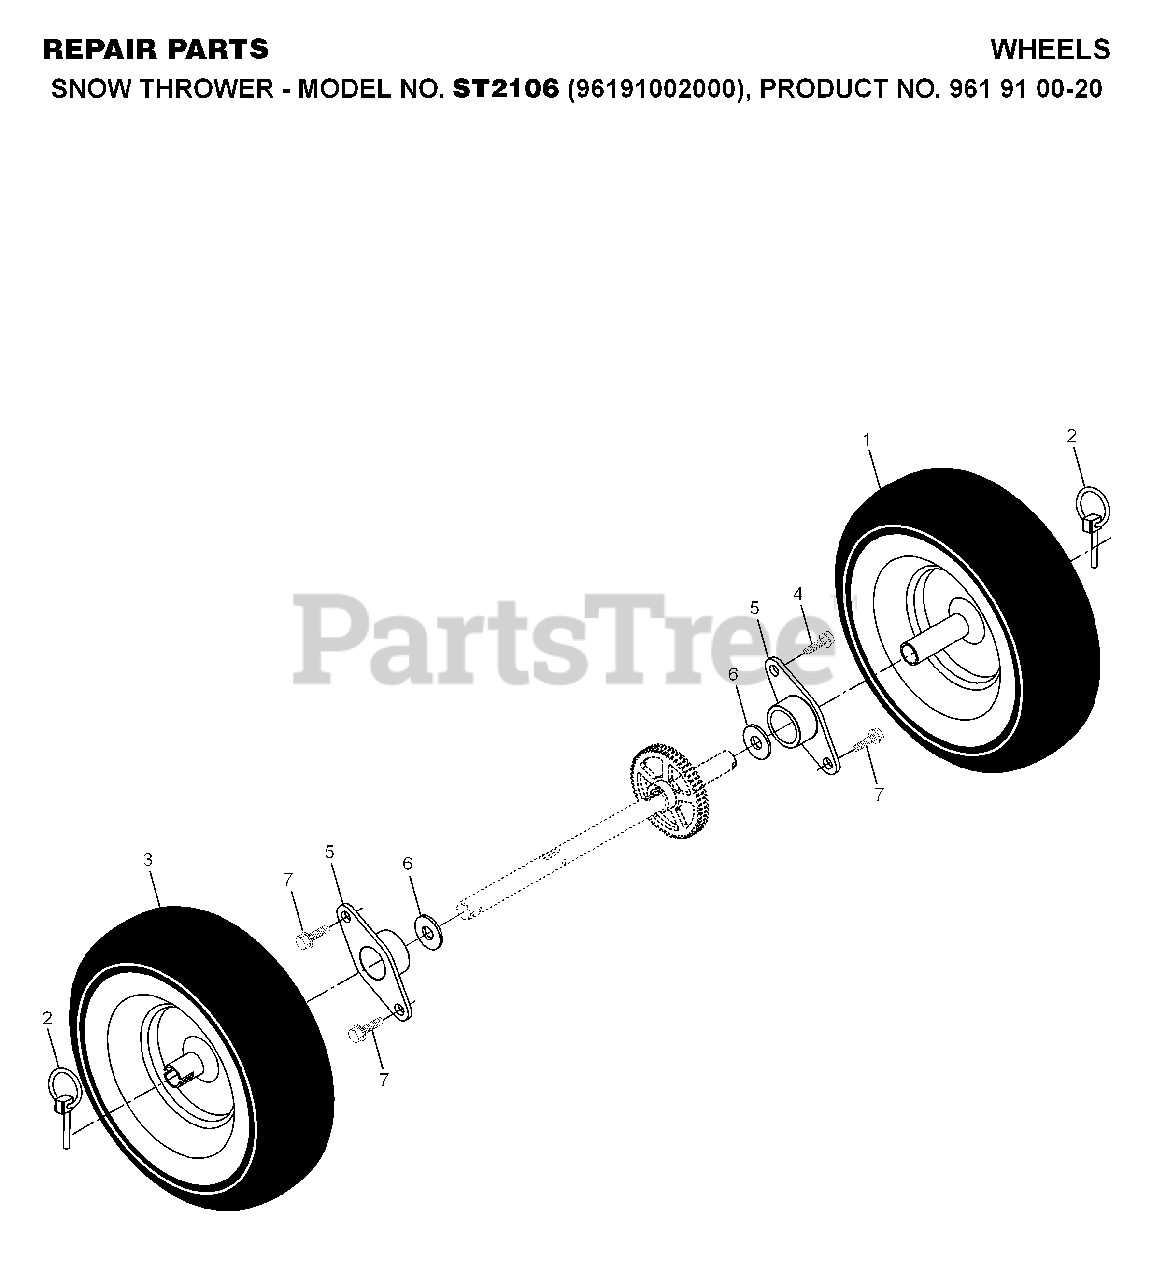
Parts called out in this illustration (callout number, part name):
1	WHEEL.ASM.LT.16"GRY.XTRAC
2	PIN KLIK, 1/4
3	WHEEL.ASM.RT.16".GRAY.XTRAC
5	BEARING, AXLE
6	WASHER TRUST 1"
7	SCREW LT
